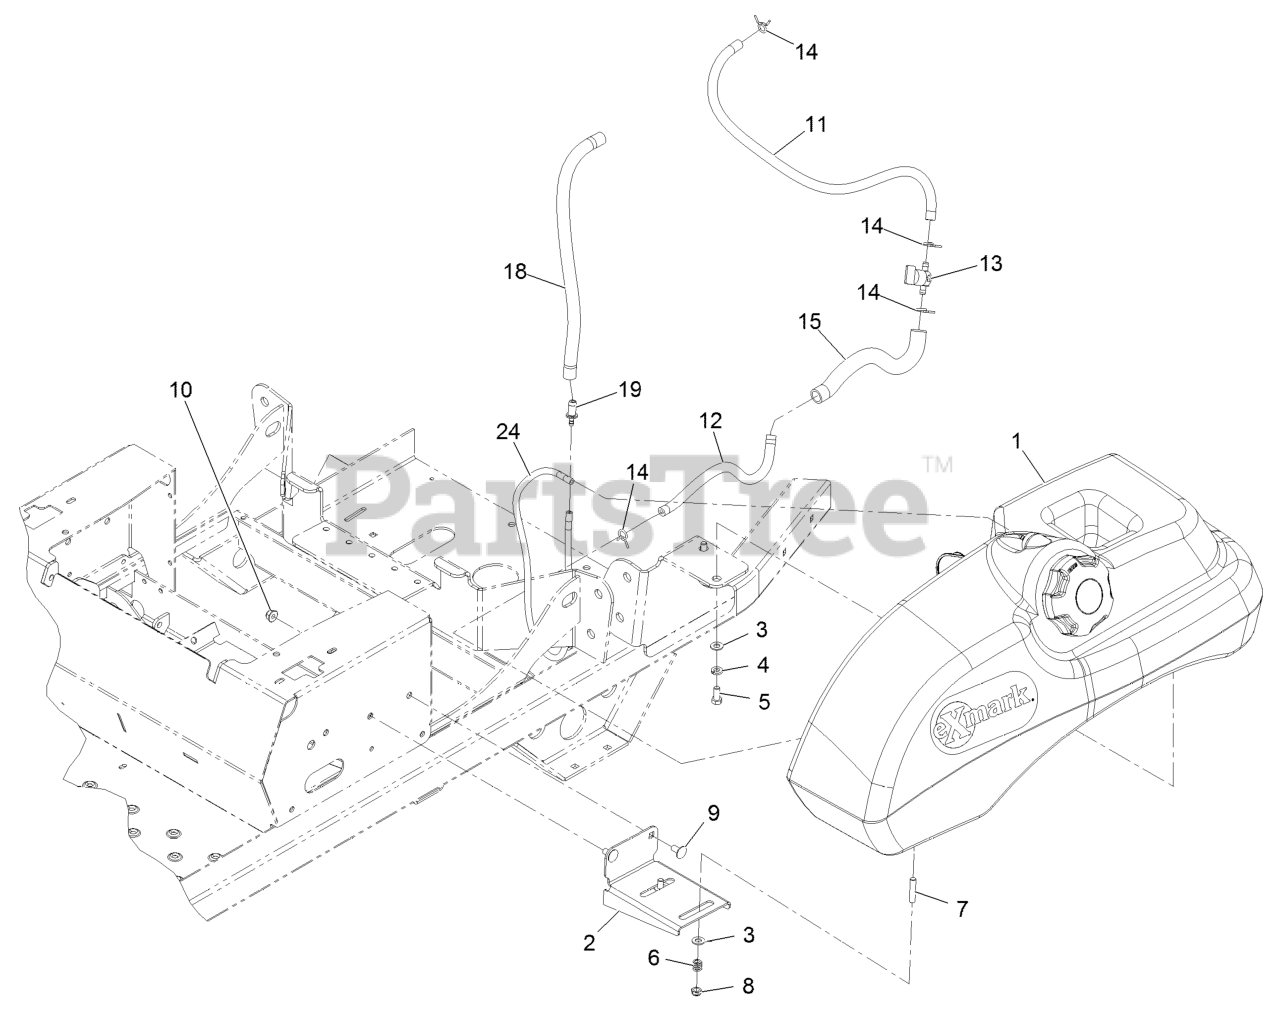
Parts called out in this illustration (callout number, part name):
1	ASM-FUEL TANK
2	BRACKET-TANK AND FENDER
3	WASHER-PLAIN
4	WASHER-LOCK
5	SCREW-HH
6	SPRING-TANK, FUEL
7	STUD
8	NUT-LOCK, NI
9	SCREW-CARR
10	NUT-HF, NI
11	HOSE-FUEL
12	HOSE-FUEL
13	VALVE-FUEL
15	CONDUIT-FUEL LINE
18	HOSE-FUEL
19	FITTING-ORIFICE, STRAIGHT
24	HOSE,EMISSIONS
